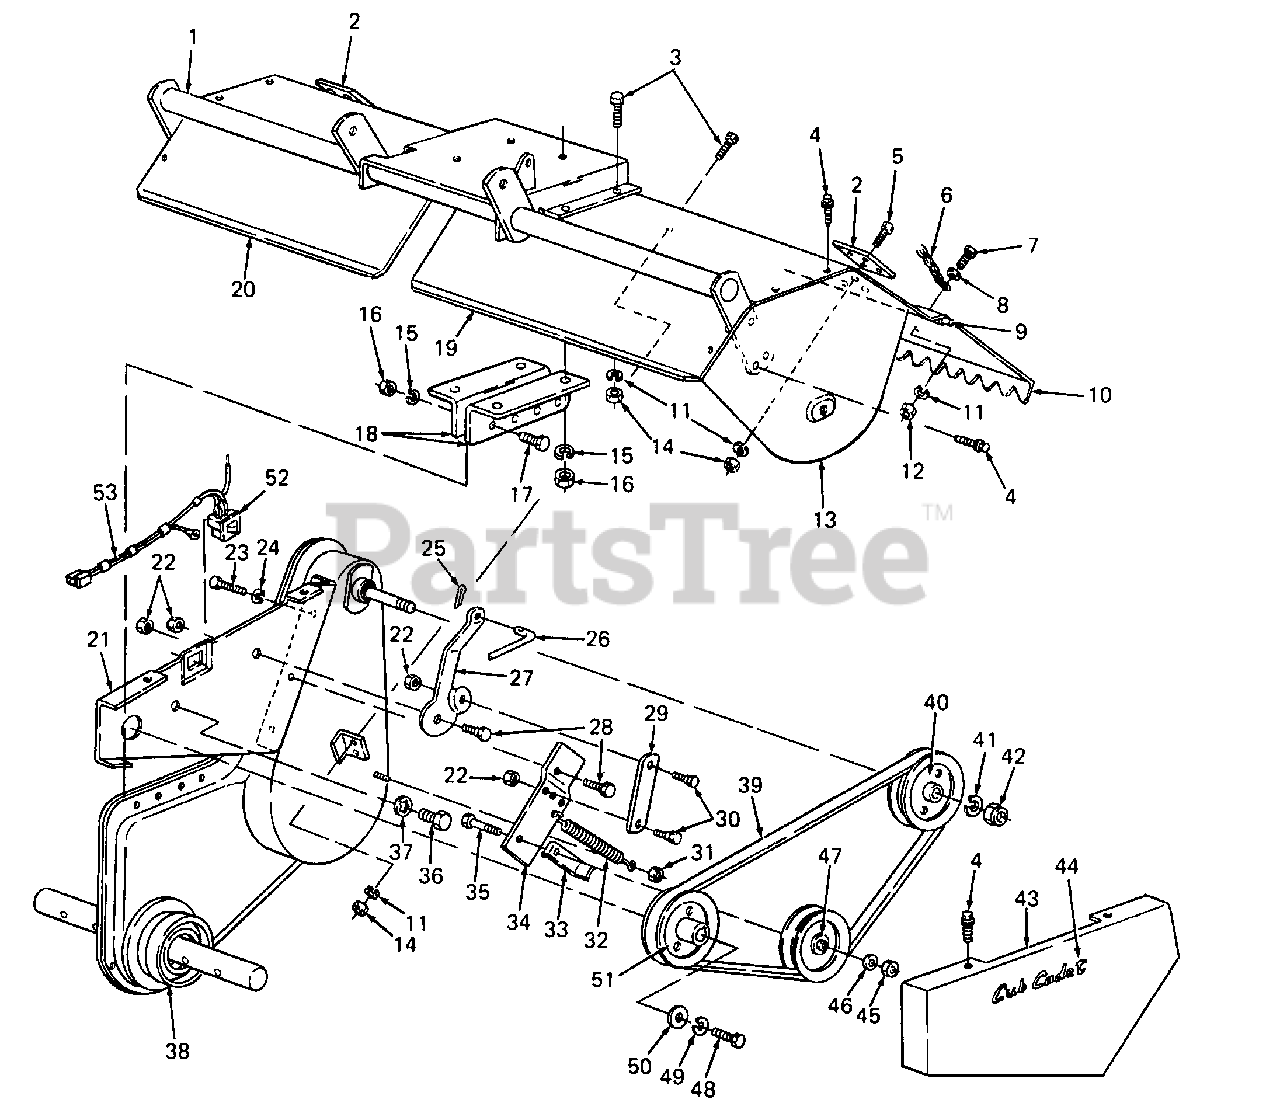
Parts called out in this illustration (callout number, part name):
4	Screw, Hex Wash Hd Tapp, 1/4 X .62 Lg
5	Screw, Hex Cap, 1/4-28 X .75 Lg
6	Chain, #2 X 20 in. Lg
7	Screw, Hex Cap, 1/4-20 X .62 Lg
8	Washer, Flat, .281 X .73 X .063 Thk
9	Rod, L.H. Flap
11	Washer, Lock, 1/4
12	Nut, Hex, 1/4-20
15	Washer, Lock, 5/16
16	Nut, Hex, 5/16-18
17	Screw, Hex Cap, 5/16-18 X 1.0 Lg GR5
18	Bracket, Engine Mounting
22	Nut, Hex Center Lock, 5/16-18
23	Screw, Hex Cap, 3/8-16 X .62 Lg
24	Washer, Lock, 3/8
25	Pin, Cotter, 1/8 Dia X 1.00 Lg
26	Rod, Clutch
31	Nut, Hex Center Lock, 3/8-24
32	Spring, Extension, .62 OD X 6.12 Lg
36	Screw, Hex Cap, 1/2-20 X .88 Lg GR5
37	Washer, Lock, 1/2
40	Pulley, 5/8 V X .625 ID X 4.75 OD
41	Washer, Lock, 5/8
42	Nut, Hex Insert Lock, 5/8-18
44	Graphic, Cub Cadet Script
45	Nut, Hex Center Lock, 3/8-16
46	Washer, Flat, .385 X .62 X .063
47	Idler Pulley, 5/8 V X 4.0 OD
48	Screw, Hex Cap, 7/16-20 X 1.0 Lg
49	Washer, Lock, 7/16
50	Washer, Flat, .44 X 1.25 X .48 Thk
51	Pulley, 5/8 V X 1.0 ID X 4.75 OD
52	Switch, Rocker
53	Harness, Safety Switch
